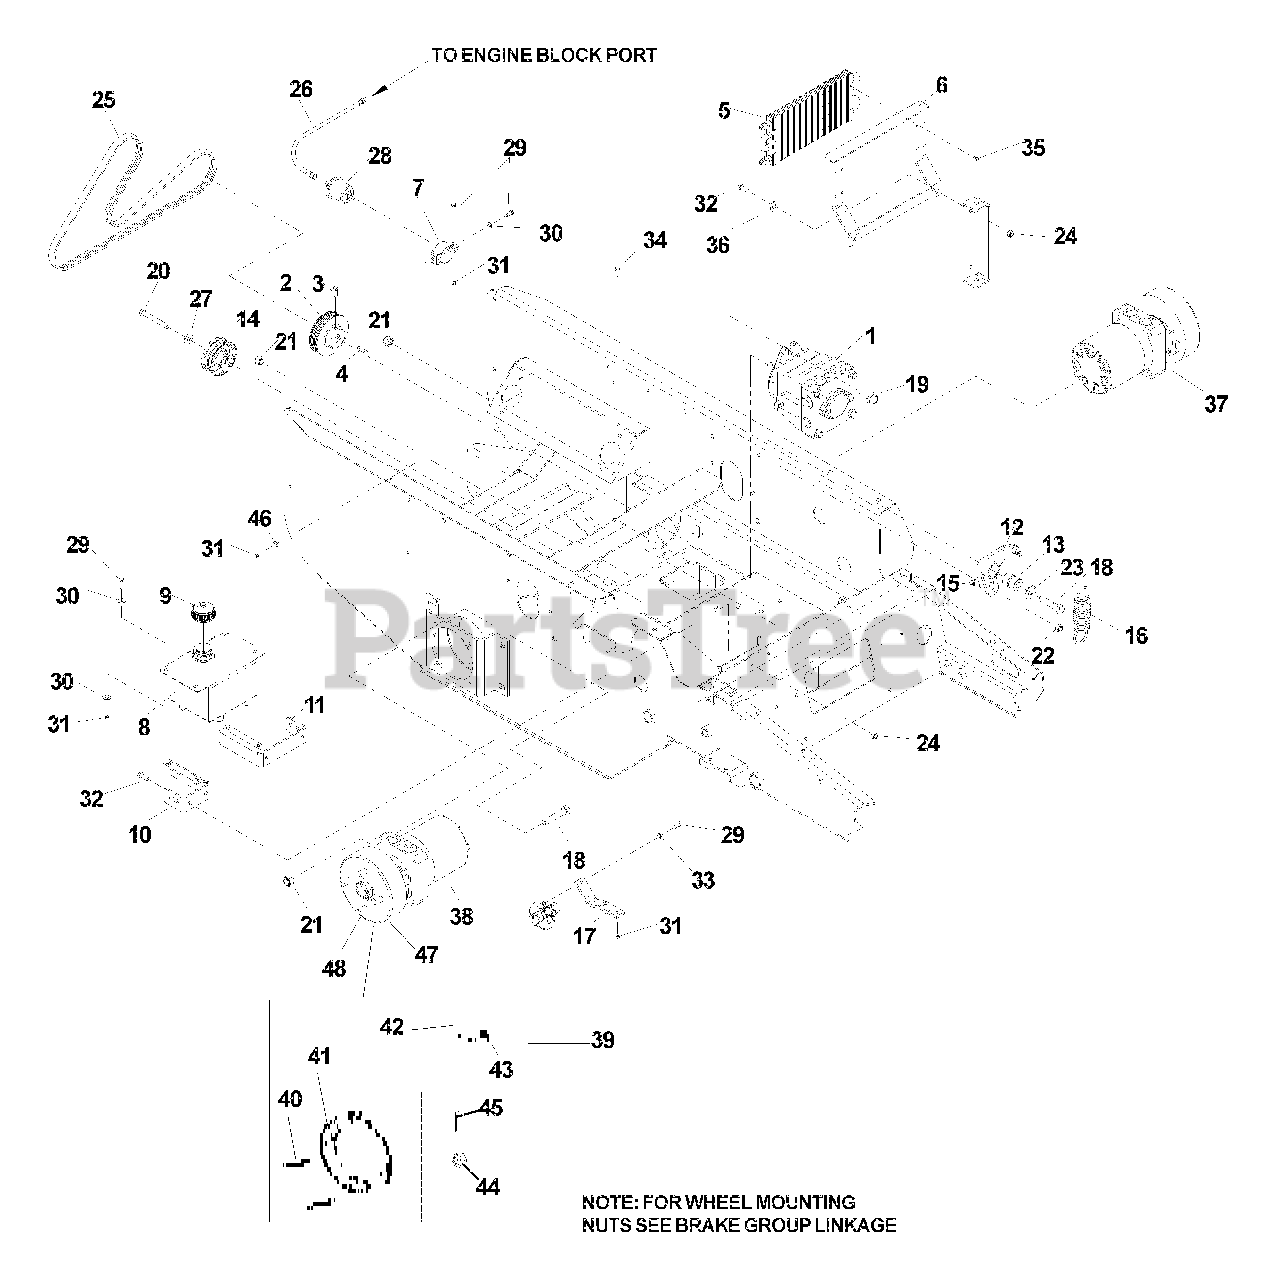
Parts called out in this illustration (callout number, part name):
2	Sheave, pump
3	Setscrew, 5/16-18 x 1
4	Key, metric
6	Mount, cooler
7	Clamp, oil sender
10	Tank mount, right
11	Tank, mount, left
14	Pulley, idler
17	Mount, filter
18	Bolt, 1/2-13 x 2 1/2
19	Bolt, 1/2-13 x 1 1/4, serrated head
20	Bolt, 3/8-16 x 3
21	Nut, 1/2-13, nyloc
22	Nut, 3/8-16, nyloc
23	Washer, 1/2
24	Nut, 5/16-18, nyloc
25	Belt, pump
27	Washer, 3/8, SAE
28	Sender, oil pressure
29	Bolt, 1/4-20 x 3/4
30	Washer, 1/4
31	Nut, 1/4-20, nyloc
32	Bolt, 5/16-18 x 1
33	Lockwasher, 1/4
34	Bolt, 1/4-20 x 1
35	Screw, #10 -12 x 3/4
36	Washer, 5/16
37	Wheel motor, left
38	Wheel motor, right
39	Shoe assembly, complete,
40	Return spring
41	Shoe assembly
44	Castle nut
45	Cotter pin
46	Washer, 1/4, external star
47	Brake drum w/studs
48	Wheel stud, 1/2-20 x 1 3/8, Gr8
